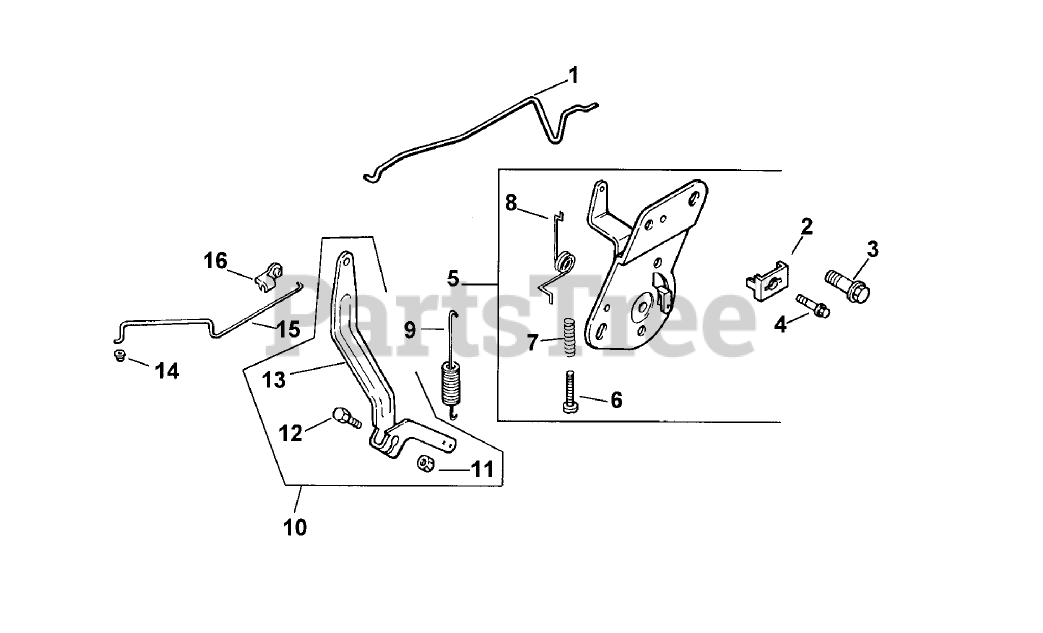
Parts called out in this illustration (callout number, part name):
1	Linkage Choke
2	Clamp
3	Screw Socket
4	Screw
5	Control-Speed
6	Screw
7	Spring
8	Spring Choke
9	Spring-Governor
10	Kit-Governor Lever (Incl. Ref.#11-13)
11	Nut
12	Bolt
13	Lever-Governor
14	Bushing-Linkage
15	Linkage-Throttle
16	Bushing-Linkage
